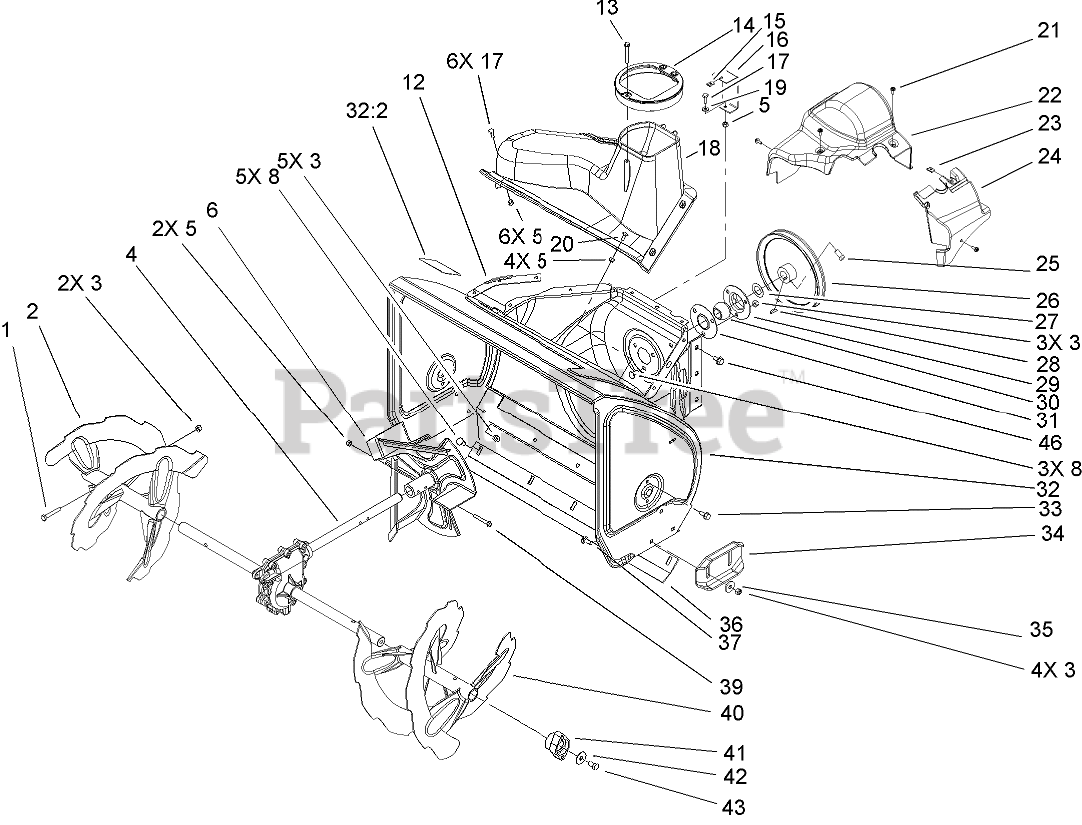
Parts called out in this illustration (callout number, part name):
1	SCREW-HH
2	RH AUGER ASM
3	NUT-LOCK, NI
4	AUGER GEARCASE ASM
5	NUT-LOCK, NI
6	IMPELLER ASM
8	SCREW-CARR
12	SEAL-FLANGE, COVER
13	SCREW-PLASTITE
14	GUIDE-CHUTE
15	NUT-SPEED, U-TYPE
16	BRACKET-COVER, CLIP NUT
17	SCREW-HH
18	COVER
19	WASHER-FLAT
20	BOLT-CARR
21	SCREW-HWH
22	COVER-BELT
23	NUT-SPEED
24	COVER-EXTENSION, BELT
25	SCREW-SET, SQH
26	PULLEY-IMPELLER
27	WASHER-THRUST
28	KEY-WOODRUFF
29	FLANGE-CUP, BEARING
30	BEARING-BALL
31	FLANGE-CUP, BEARING
32	HOUSING-AUGER, 28 INCH
32:2	DECAL-DANGER, AUGER
33	SCREW-HWHTF
35	WASHER
36	SCRAPER-FIXED
37	SCREW-CARR
39	SCREW-HHF
40	LH AUGER ASM
41	BEARING-AUGER
42	WASHER
43	SCREW-HH
46	SCREW-HWHTF
